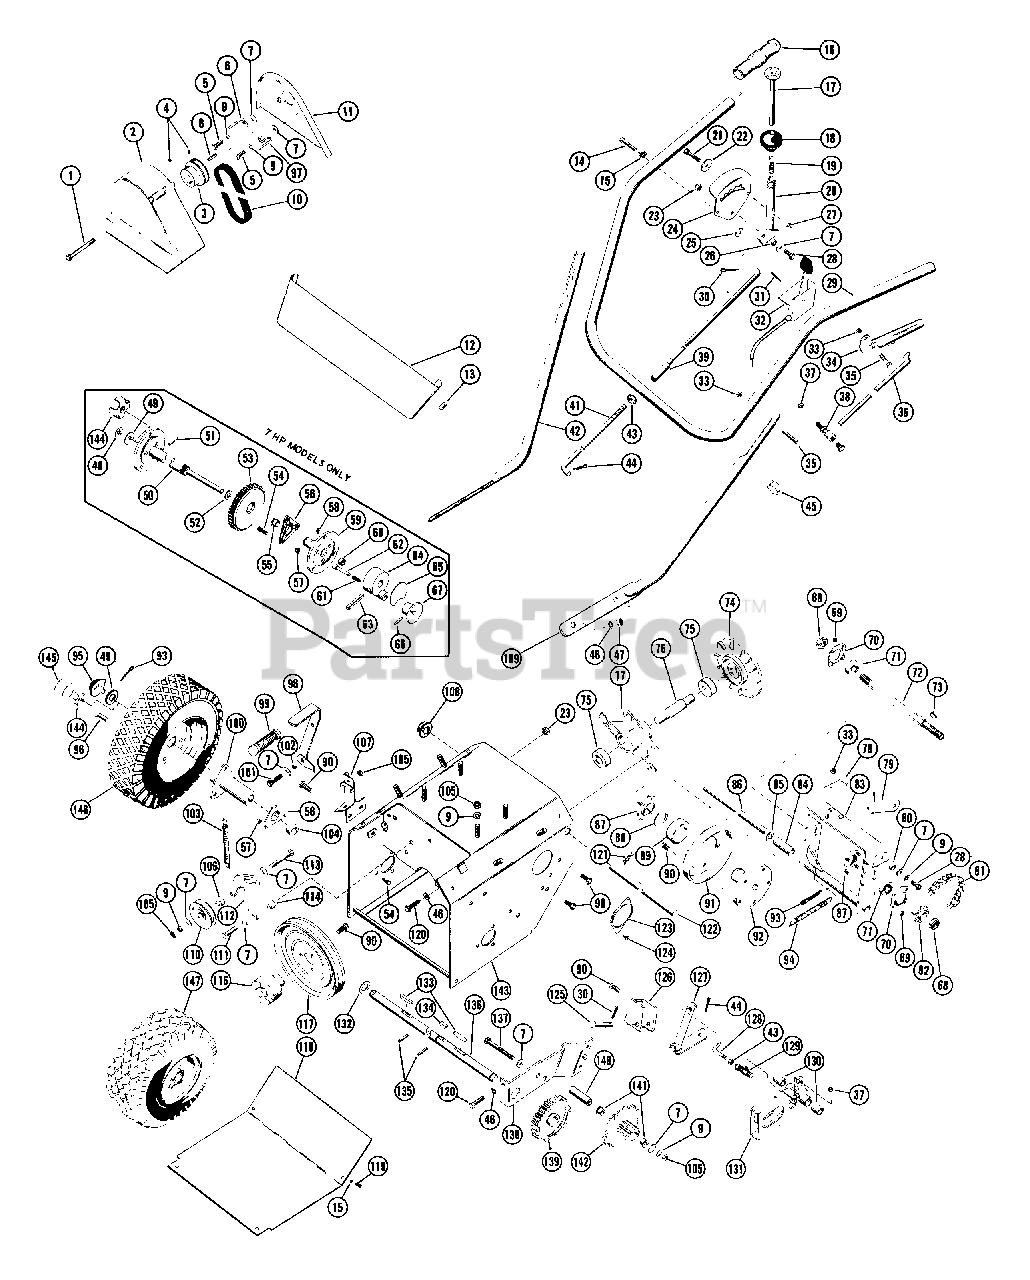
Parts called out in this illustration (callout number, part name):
1	BLT-HFWH .31-24X3.62 PL
2	OUTER COVER
3	ENGINE SHEAVE
4	SCR-SET .32-18X.38 SKHCUPNL OH
5	BLT-HEX .31-24X.75 PL GR5
6	R H BELT FINGER
7	WSHR-FL-STL .38X.875X.083 PL
8	KEY-SQ .188X1.0X.188 SAE 8630
9	WSHR-LK .312X.097 PL HVY
10	V-BELT, SAE 380-RAW EDGE
11	INNER BELT GUARD
12	HANDLE BAR PANEL
13	HANDLE BAR WASHER
14	BLT-HEX .25-20X1.25 PL GR5
15	WSHR-LK .250X.077 HVY PL
16	GRIP
17	SHIFT RELEASE HANDLE
18	SHIFT BALL
19	SG-COMP ??X.44X?? WLD 10
20	SHIFT HANDLE
21	BLT-HEX .25-20X1.25
22	WSHR-FL-STL .281X1.250X.048PL
23	NUT-LK .312-18 GR A PL
24	SHIFT QUADRANT
25	WSHR-FL-STL.406X.812X.065PL
26	SPACER BUSHING .5 X .32 X .21
27	NUT-LK TOP .250-20 PL
28	BLT-HEX .31-18X.75 PL GR2
29	UPPER HNDLBAR PLATED
29	UPPER HANDLE BAR
30	PIN-COTR .12X1.0 PL
31	SCR-TAP 10-12X.50 CRPH PL A
32	THROTTLE CONTROL
33	NUT-LK-CTR .250-20 PL
34	CLUTCH HANDLE
35	BLT-HEX .25-20X1.50 PL GR5
36	CLTCH ROD
37	NUT-LK-CTR .312-24 PL
38	BALL JOINT
39	SHIFT ROD
41	LOWER SHIFT ROD
42	R H LOWER HANDLE BAR
43	NUT-HEX .312-24 PL
44	PIN-COTR .09X.75 PL
46	WSHR-LK .375X.115 HVY PL
47	NUT-HEX .375-16
48	PUSHNUT
49	WSHR-FL-STL .755X2.000X.125
50	R H AXLE SHAFT
51	PIN-ROLL .188X1.25
52	WSHR-FL-STL .880X1.380X.062
53	DIFFERENTIAL ASSEMBLY
54	SCR-SLTR-SERNK .25-20X.62 PL
55	BSHG-FLG.875X1X.625X1.250 BR
56	SUPPORT, BEARING
57	NUT-LK-FLG .250-20 PL
58	HYDRAULIC DRIVE FITTING
59	L H AXLE ASSEMBLY
60	BSHG-SLV .562X.625X.625 BRZ
61	SG-COMP .028X.34X1.062 WLD75
62	PIN
63	PIN-ROLL .250X1.75
64	LOCKOUT HUB
65	DIFFERENTIAL LOCK LABEL
66	PIN-ROLL .093X1.00
67	KNOB
68	NUT-LK-CTR .50-20 PL
69	NUT-LK TOP 10-24 PL
70	BEARING FLANGE
71	BRG-BALL .500X1.38X.437
72	HEX SHAFT
73	KEY-WDRF .125X.625X.250 SAE5
74	DRIVE PLATE
75	BRG-BALL .750X1.750X.50
76	SPINDLE
77	BEARING HOUSING
78	NEUTRAL CATCH
79	THROWOUT LEVER
80	SPACER BUSHING .5 X .32 X .163
81	ROLLER CHAIN
82	9 TOOTH SPROCKET
83	DISC BRCKT
85	WSHR-FL-STL .505X.875X.024 PL
86	BRACKET PIN
87	BEARING FLANGE
88	RG-RTNG-EXT 1.250X.050
89	BRG-N-THRST 1.26X2.18X.63
90	BLT-SERHFWH .31-18X.50 PL
91	FRICTION DISC
92	FRICTION DISC HUB
93	PIN-COTR .12 X 1.25 PL
94	SG-TENS .080X.470X4.88 WLD 30
95	HUB CAP
96	BLT-WHL .50-20X.50 GR5 PL
97	L H BELT FINGER
98	CLTCH LEVER
100	WHEEL HUB
101	BLT-HEX .31-18X1.00 PL GR 2
102	SPACER .50 X .32 X .42
103	SG-TENS .125X.437X5.5 WLD 20
104	BSHG-FLG .750X1.000X.625X1.250
105	NUT-HEX .312-18
106	BEARING SPACER
107	CLTCH BRCKT
108	CAP, .50 ROD YWZC
109	L H LOWER HANDLE BAR
110	IDLER
111	BLT-HEX .31-18X1.25 PL GR2
112	IDLER ARM
113	BLT-HEX .31-18X1.75 PL GR2
114	SHOULDER SPACER
116	JAW COUPLING
118	BOTTOM COV
119	BLT-HEX .25-20X.50 PL GR2
120	BLT-HEX .38-16X.75 PL GR2
121	PIN-HAIR INT .08X.38X1.42 YWZC
122	FORK SHAFT
124	SCR-TAP 10-24X.25 CRSLPH PL 1A
125	CLEVIS PIN
126	LEVER BRACKET
127	TRANSFER LEVER
128	CONNECTING LINK
129	BALL JOINT
130	BSHG-SLV .500X.625X.500 BR
131	SLIDING FORK
132	WSHR-FL-STL .755X1.375X.125 PL
133	KEY-FTHR .188X1.25X.187 SAE
134	KEY-WDRF .25X.750X.313 SAE91
135	PIN-ROLL .188X1.00
136	AXLE SHAFT
137	BLT-HEX .31-18X2.75 PL GR2
138	SUPPORT BRACKET
139	SPUR GEAR, FELLOWS 35T .750 ID
140	PINION STUB SHAFT
141	BSHG-FLG .625X.750X.500X.875BR
142	PINION & SPROCKET
143	TRACTOR FRAME
144	SPINDLE CUP
145	HUB CAP
146	TIRE & WHEEL ASSEMBLY GOODYEAR
146	TIRE 4.10/3.50X6
146	TIRE 4.10/3.50X6 2PLY
146	TUBE
146	WHL 6 IN O.D.
147	TIRE & WHEEL ASSEMBLY CARLISLE
147	TIRE 12.5/4.50-6
147	TUBE
147	WHL 6 IN O.D.
